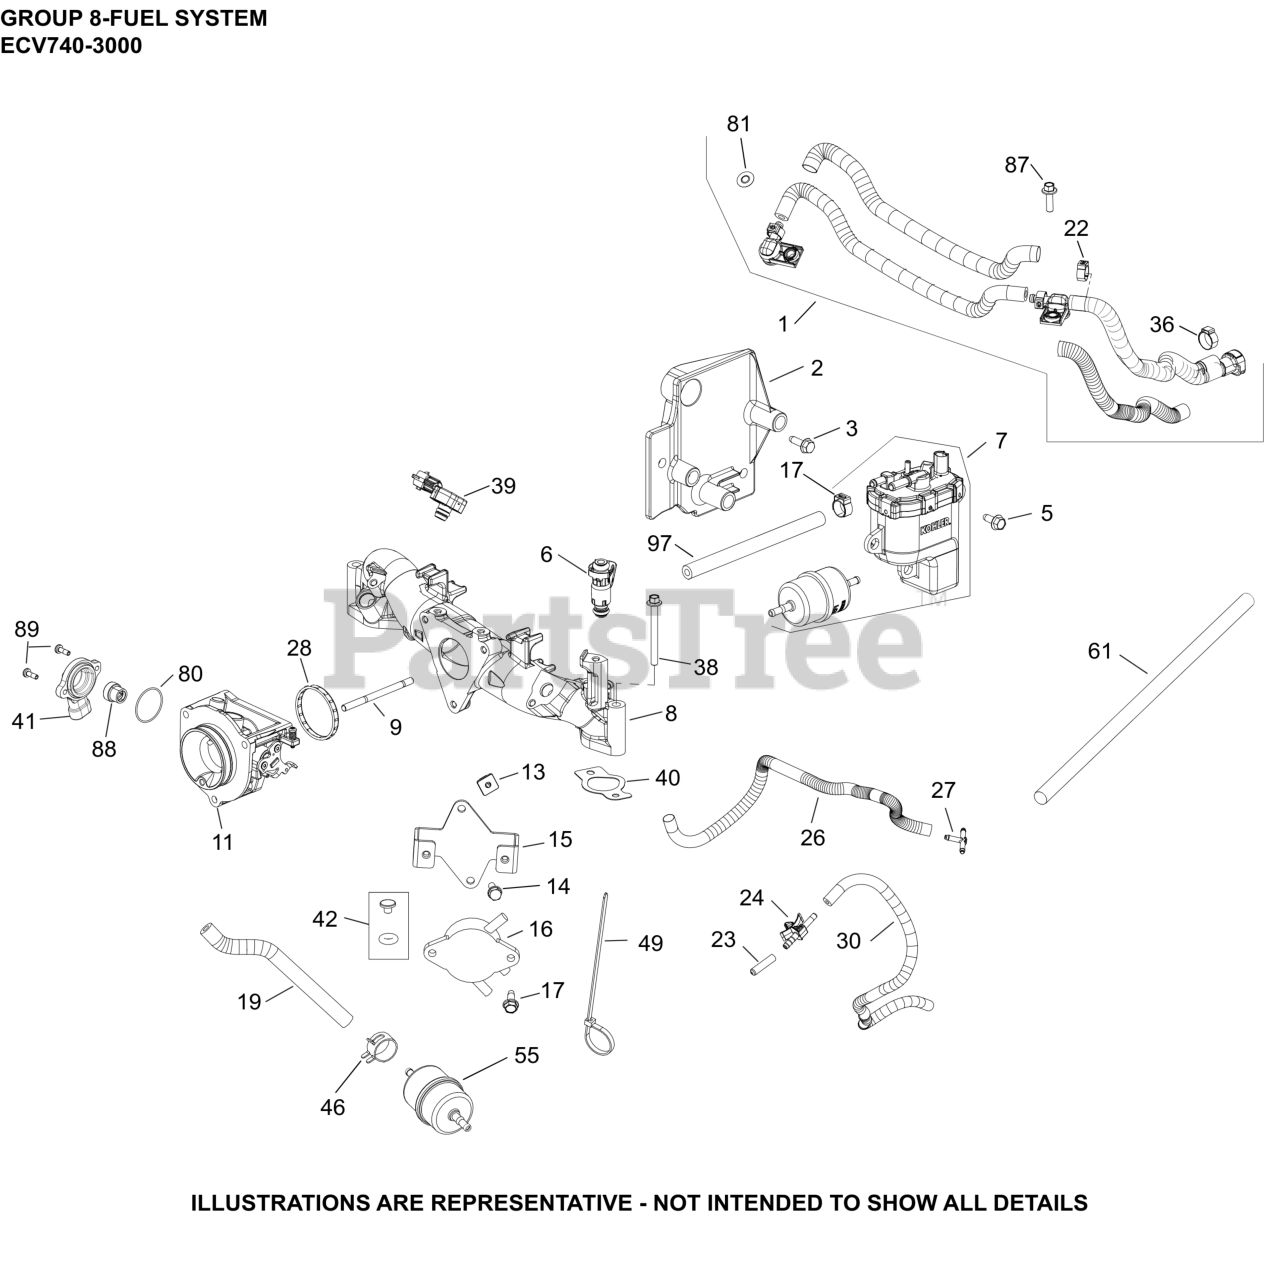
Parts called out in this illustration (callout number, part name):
1	FUEL HOSE ASSY(ECV,FCV,EZT,EKT,PCH,PCV)
2	KIT,BAFFLE, FUEL MODULE
3	SCREW, THREAD FORMING
5	SCREW, FLG M6X1.0X16
6	INJECTOR, FUEL
7	KIT, FUEL PUMP MODULE
8	KIT, MANIFOLD
9	STUD,M6X1.0X84
11	BODY, THROTTLE ASM (30)
13	NUT, PLASTIC - BLACK
14	SCREW, HEX HEAD
15	BRACKET, FUEL PUMP MOUNTING
16	PUMP, FUEL
17	SCREW, THREAD FORMING
19	HOSE,LW PERM.FUEL 24.00"-USE 25 111 81-S
22	CLAMP, OETIKER
23	CAP, MASKING
24	CONNECTOR, EVAPORATIVE
26	SLEEVE, ANTI-ABRASION
27	TEE CONNECTOR
28	O-RING, THROTTLE BODY
30	HOSE, EVAPORATIVE (15.0)
36	CLAMP, HOSE
38	SCREW, FLG M6X1.0X60
39	SENSOR, T-MAP
40	KIT, INTAKE MANIFOLD GASKET
41	SENSOR, THROTTLE POSITION
42	KIT, FUEL INJECTOR O-RING
46	SPRING CLAMP, HOSE
55	FILTER, FUEL
61	SLEEVE, ANTI ABRASION -USE 25 431 12-S
80	O-RING, TPS SENSOR
81	CLIP, RETAINER
87	SCREW, FLG M6x1.0x20
88	MAGNET ASSEMBLY, TPS
97	HOSE, FUEL LOW-PERMEATION
NI	SLEEVE, ANTI ABRASION-USE 25 431 12-S
